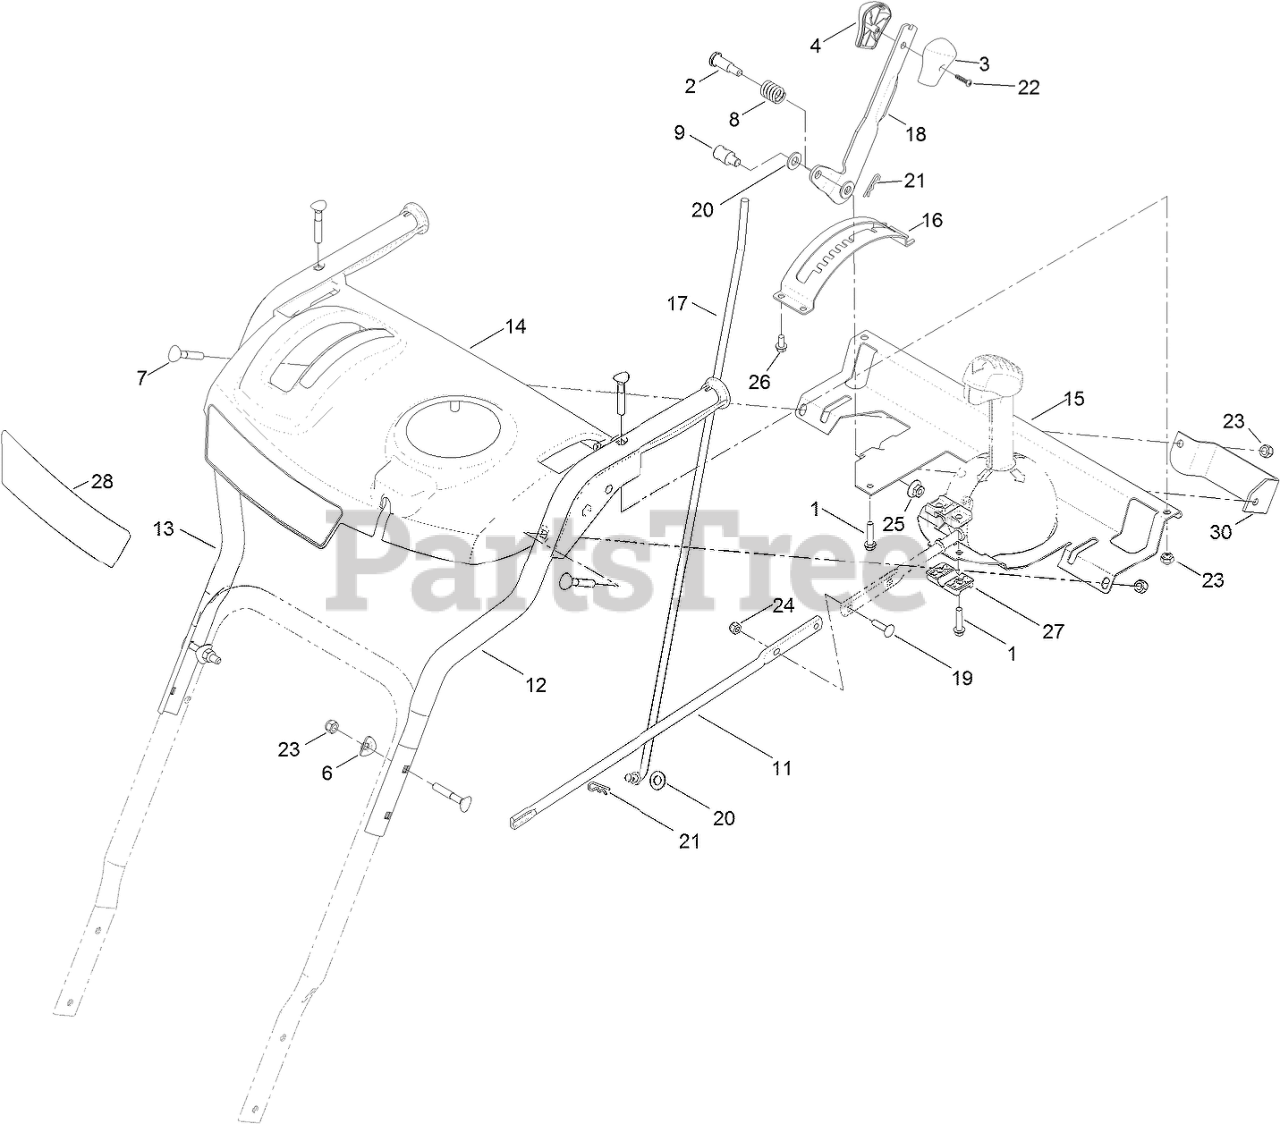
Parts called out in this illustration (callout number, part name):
1	SCREW-PLASTITE
2	SCREW-SHOULDER
3	KNOB-SHIFT, LH
4	KNOB-SHIFT, RH
6	WASHER
7	SCREW-HANDLE
8	SPRING-COMPRESSION
9	TRUNNION-ROD
11	ROD-CHUTE, FRONT
12	HANDLE-UPPER, LH
13	HANDLE-UPPER, RH
14	PANEL-CONTROL, MASTER
15	SUPPORT-PANEL, CONTROL
16	MOUNT-SELECTOR, SPEED
17	ROD-SELECTOR, GEAR
18	SELECTOR-SPEED
19	SCREW-CARR
20	WASHER-FLAT
21	PIN-COTTER
22	SCREW-PPH
23	NUT-LOCK, NI
24	NUT-LOCK, NI
25	NUT-HF
26	SCREW-PLASTITE
27	SUPPORT-ROD
28	DECAL-MODEL
30	PLATE-SUPPORT, SHIFT
